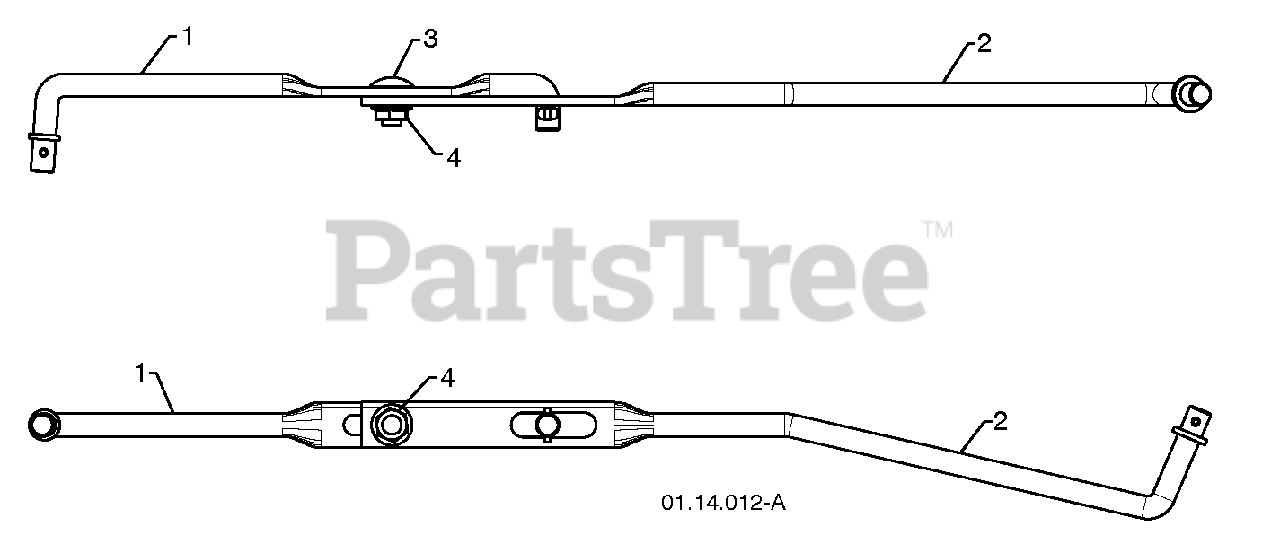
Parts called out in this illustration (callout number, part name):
1	SHIFTER ROD TOP
2	SHIFTER ROD BOTTOM
3	CARRIAGE BOLT 5/16-18 X .75
4	NUT 5/16-18
